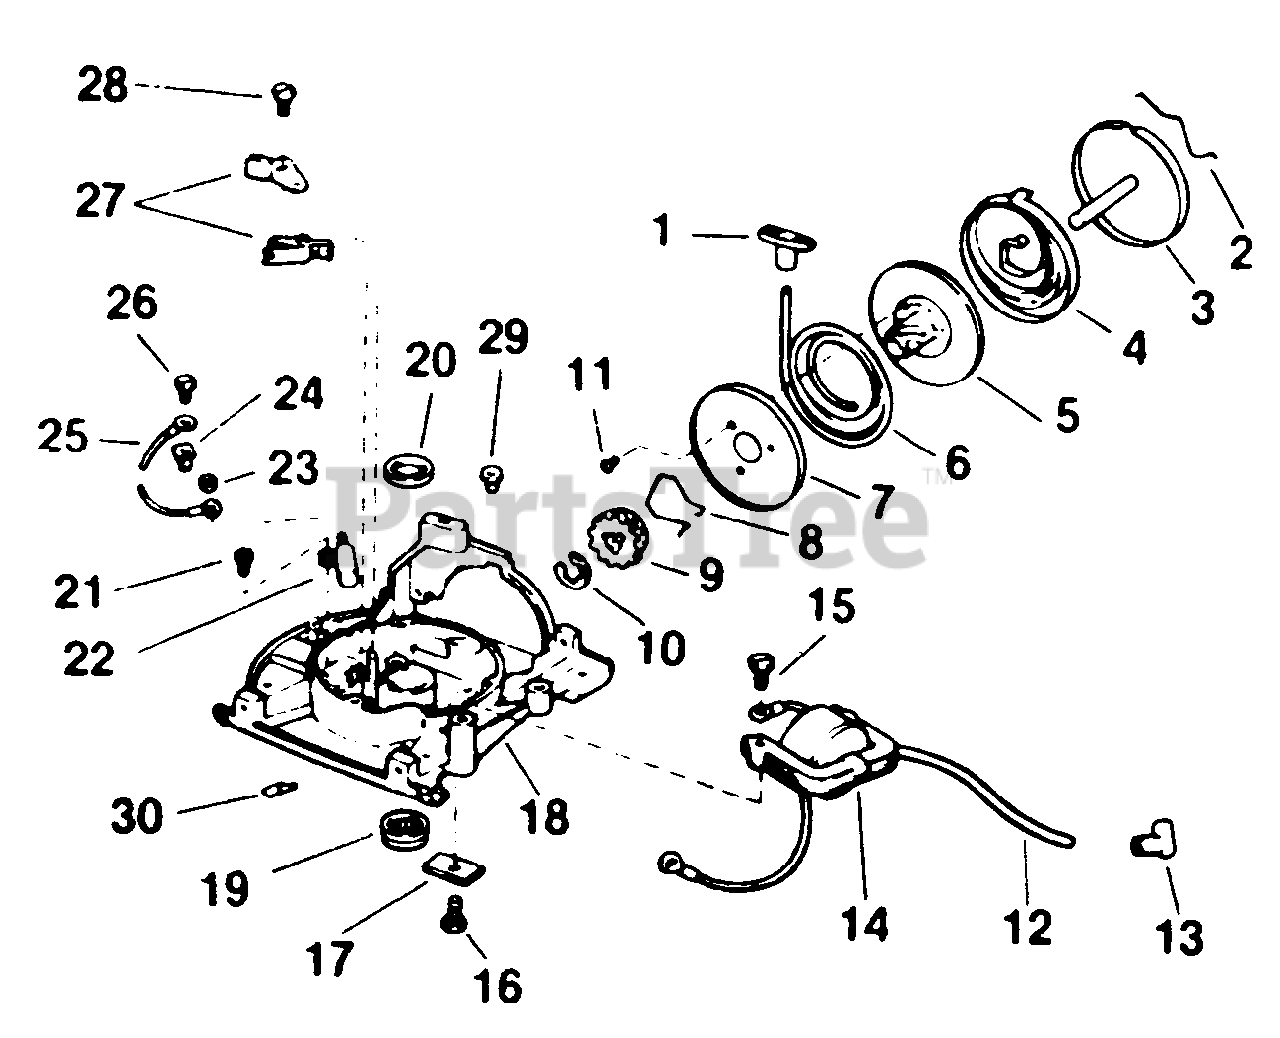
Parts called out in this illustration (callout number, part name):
1	Handle-Starter
2	Spring-Starter Rope Retainer
3	Spring-Cup-Pin Assy.
4	Spring-Starter
5	Pulley-Starter
6	Rope-Starter
7	Plate-Starter Pulley
8	Spring-Starter Pinion
9	Pinion-Starter
10	Retainer-Push-On
11	Screw-Threaded Cutting Starter
12	High Tension Lead Assy.
13	Cover and Terminal Assy.
14	Coil & Lamination Assy.
15	Screw-Lamination Mtg.
16	Screw-Starter Attach.
17	Clamp-Starter Pin
18	Arm. Pl., Brg. & Oil Seal Assy.
19	Bearing
20	Oil Seal
21	Screw-Cond-Mtg.
22	Cond. & Nut Assy.
24	Grommet-Nylon
25	Terminal & Lead Assy.
26	Screw-Shut-Off Sw.
27	Brkr. Base & Arm Assy.
29	Grommet
